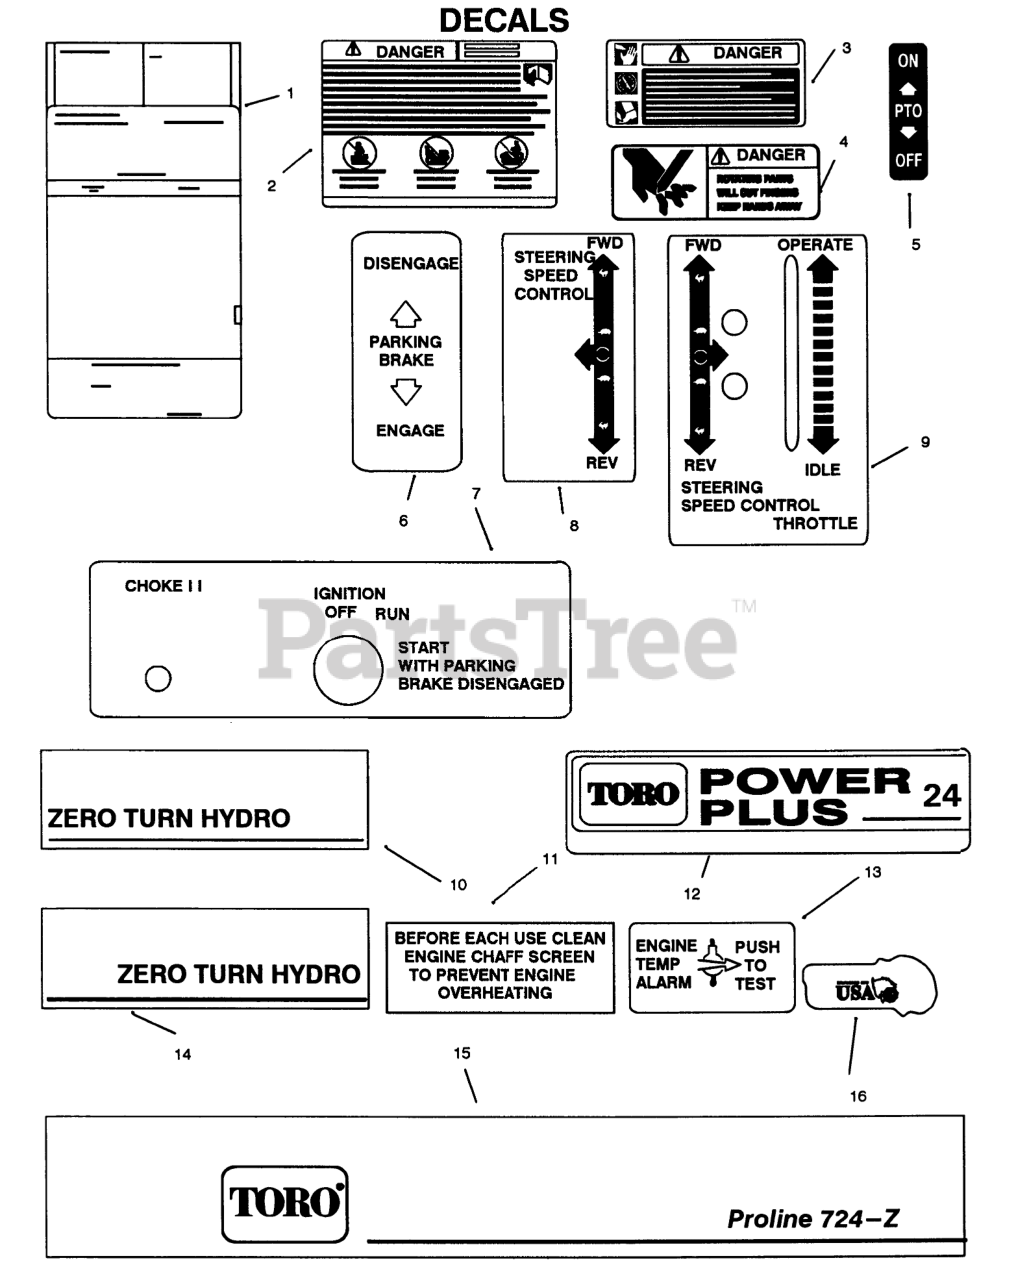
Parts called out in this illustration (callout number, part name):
1	Decal-Maintenance
2	DECAL-DANGER
3	DECAL-DANGER
4	DECAL - DANGER
5	DECAL-PTO
6	DECAL-PARKING BRAKE
7	DECAL-CHOKE/IGNITION
8	DECAL-STRG SPEED CNT
9	DECAL THROTTLE
10	DECAL-ZERO TURN R.H.
11	DECAL-ENGINE SCREEN
12	DECAL-PWR PLUS 24 PL
13	DECAL-TEMP ALARM
14	DECAL-ZERO TURN L.H.
15	DECAL-TORO 724-Z
16	DECAL-MADE IN USA BK
